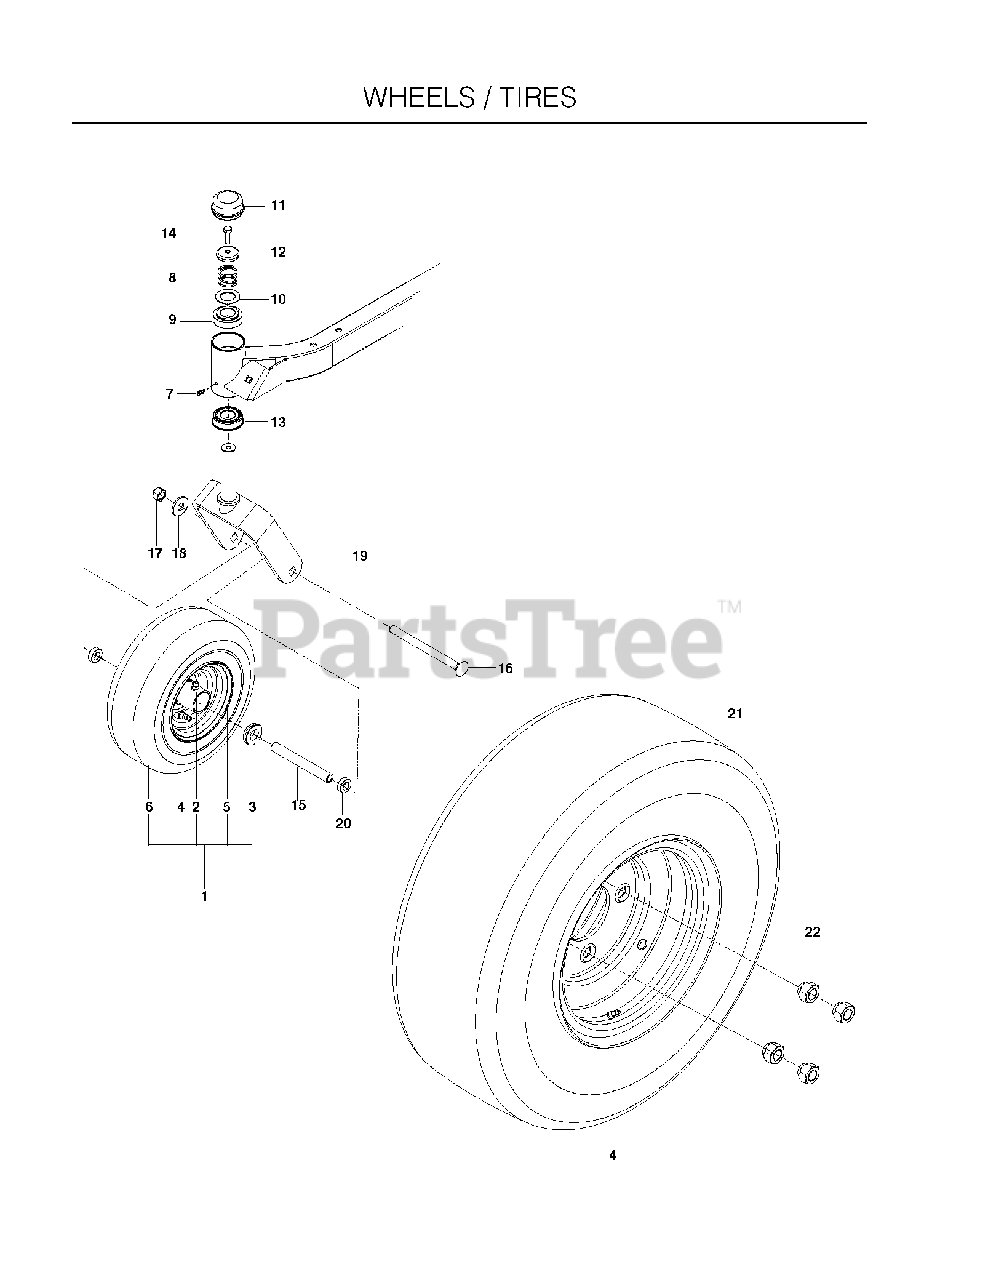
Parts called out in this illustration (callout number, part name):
1	TIRE.CASTER.ASSEM.11X4-5.GREY
2	ZERK
3	BEARING RETAINER
4	VALVE STEM TR-412
6	TIRE.11"X4"-5.4PLY.SMOOTH.KEND
7	ZERK, 3/16, DRIVE IN
8	SPRING, CASTER
9	BUSHING, CASTER
10	WASHER, 1.025 ID X 1.64
11	GREASE CAP
12	CASTER.PLUG
13	BEARING FLANGED
14	5/16-18X1 HHB G5W/NY
16	RHSNB 1/2-13 X 6.50 GR2 ZD
17	NUT 1/2-13 HEX NYLOC ZD
18	WASH USS FLAT 1/2
19	Caster Wheel Yoke, Orange
20	SPACER, 5/16"
21	REAR WHEEL AND TIRE
22	LUG NUT 1/2F
